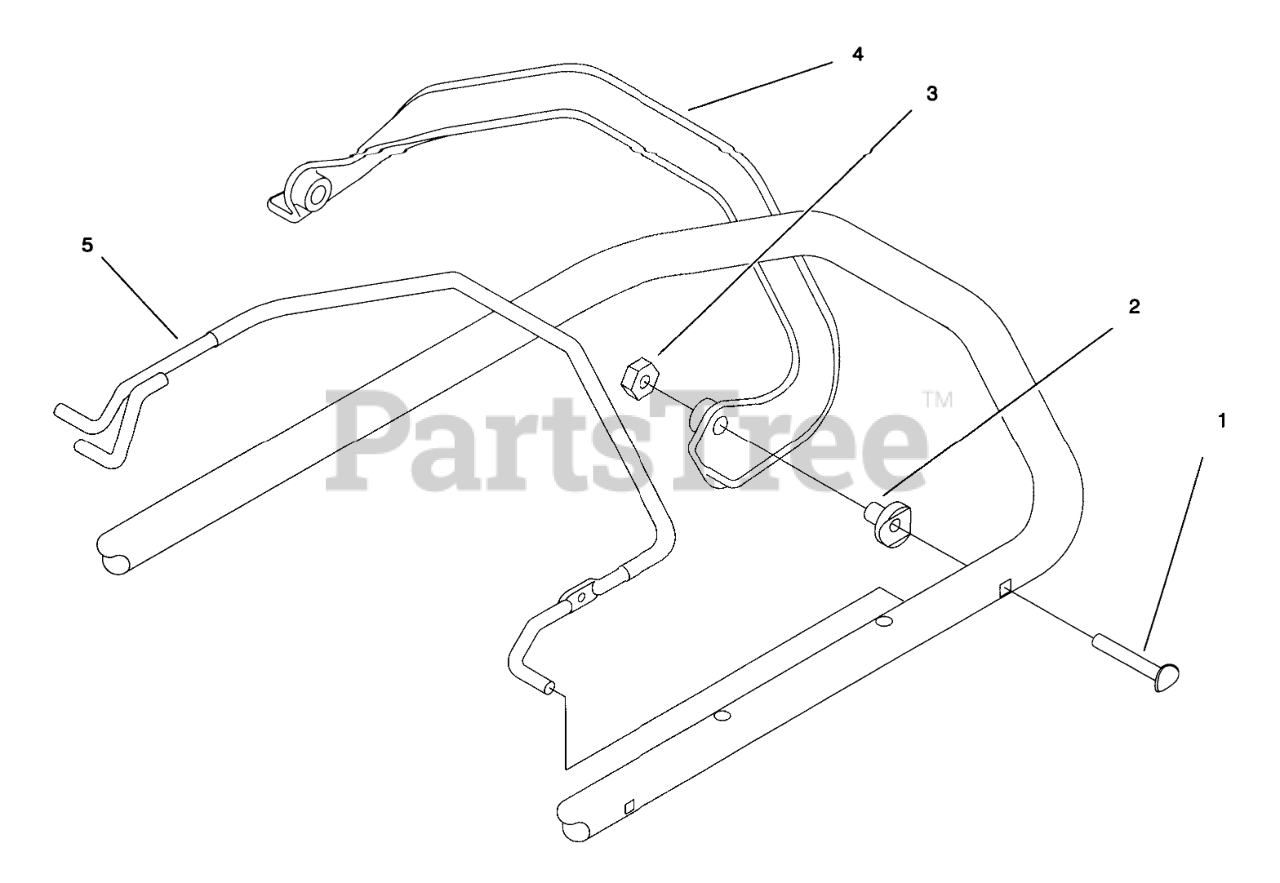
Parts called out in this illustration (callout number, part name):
1	SCREW-HANDLE
2	SPACER-SUPPORT
3	NUT-LOCK NI
4	BAIL - TRACTION
5	Bail-Brake
